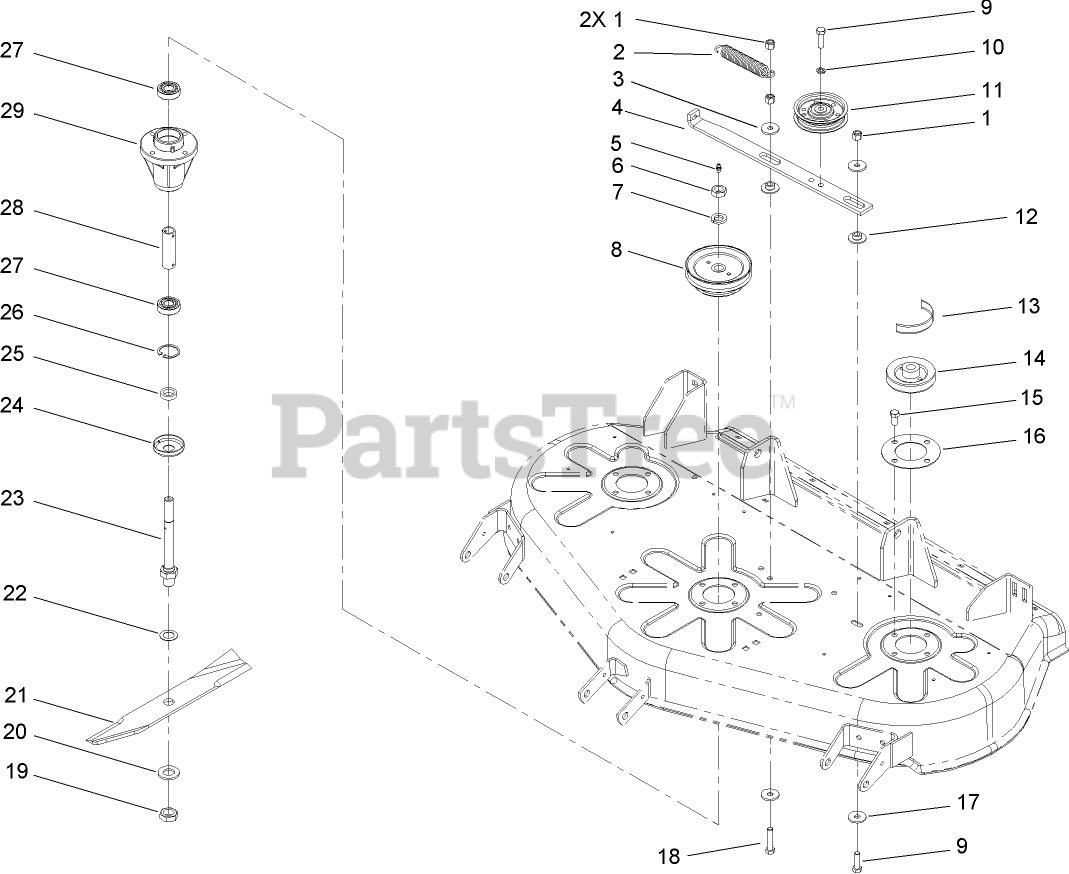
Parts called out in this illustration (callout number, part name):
1	NUT-LOCK, NI
2	SPRING-EXTENSION
3	WASHER
4	BAR-IDLER SUPPORT
5	FITTING-GREASE
6	NUT-JAM
7	WASHER-LOCK
8	PULLEY
9	SCREW-HH
10	WASHER-LOCK
11	PULLEY-IDLER, FLAT
12	SPACER-BUSHING
13	V-BELT
14	PULLEY
15	SCREW-HH
16	PLATE-SPINDLE
17	WASHER
18	SCREW-HH
19	NUT-JAM
20	WASHER-FLAT
22	WASHER-FLAT
23	SHAFT-SPINDLE
25	SPACER-BLADE
26	RING-RETAINING
27	BEARING-BALL
29	HOUSING-SPINDLE
